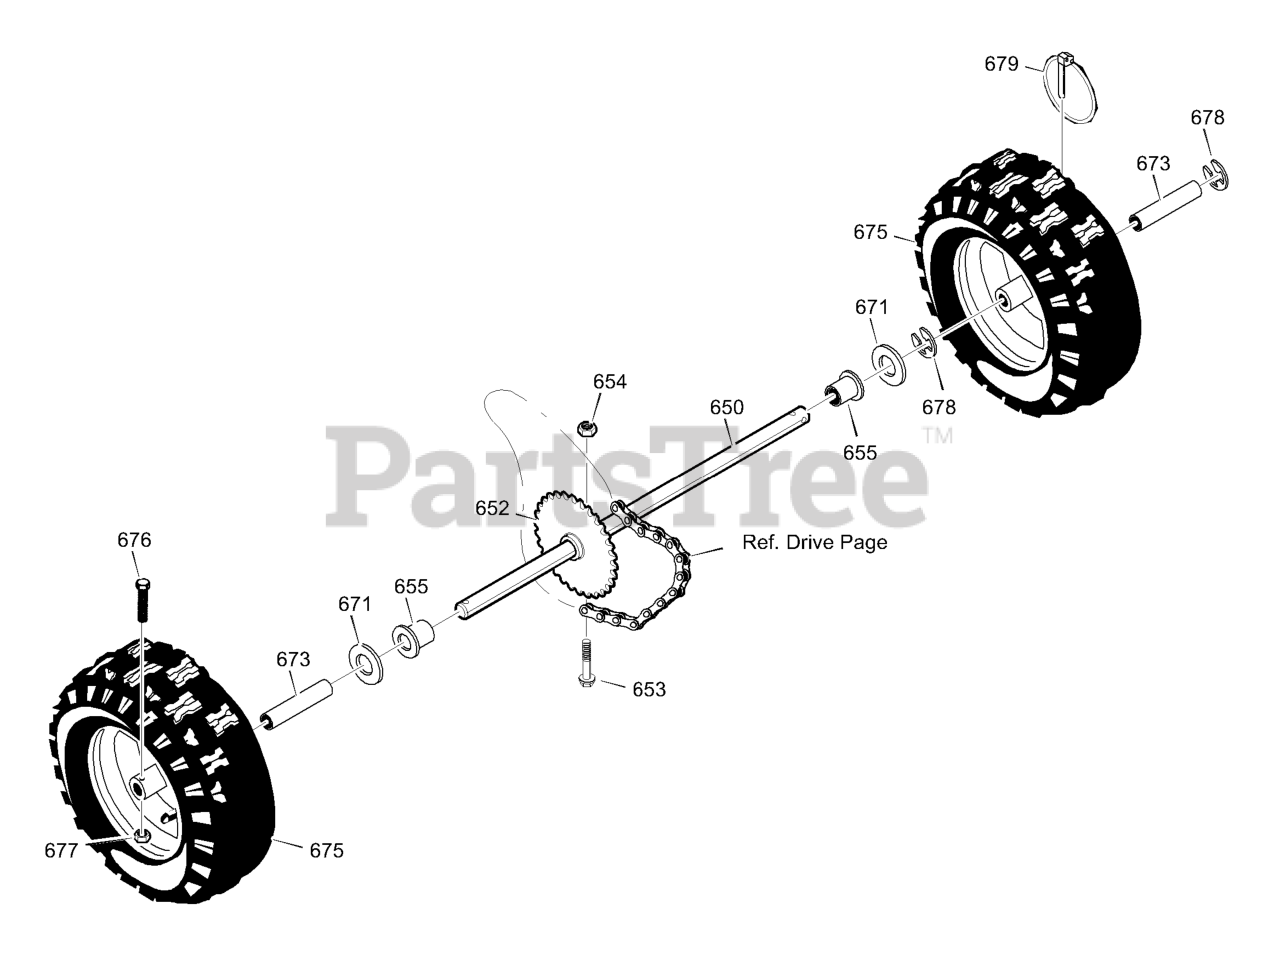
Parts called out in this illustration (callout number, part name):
650	AXLE, BEARING
652	SPRKT & HUB
653	SCREW, 1/4-20 X 1.75
654	NUT, 1/4-20 HEX NYLOCK
655	BEARING, AXLE
671	FLATWASHER
673	BUSHING, WHEEL
675	TIRE & RIM
676	SCREW, 1/4-20X1.75 HH
677	NUT, 1/4-20 HEX NYLOCK
678	RING, RET
679	PIN, KLIK .25 X 1.38 DIA
